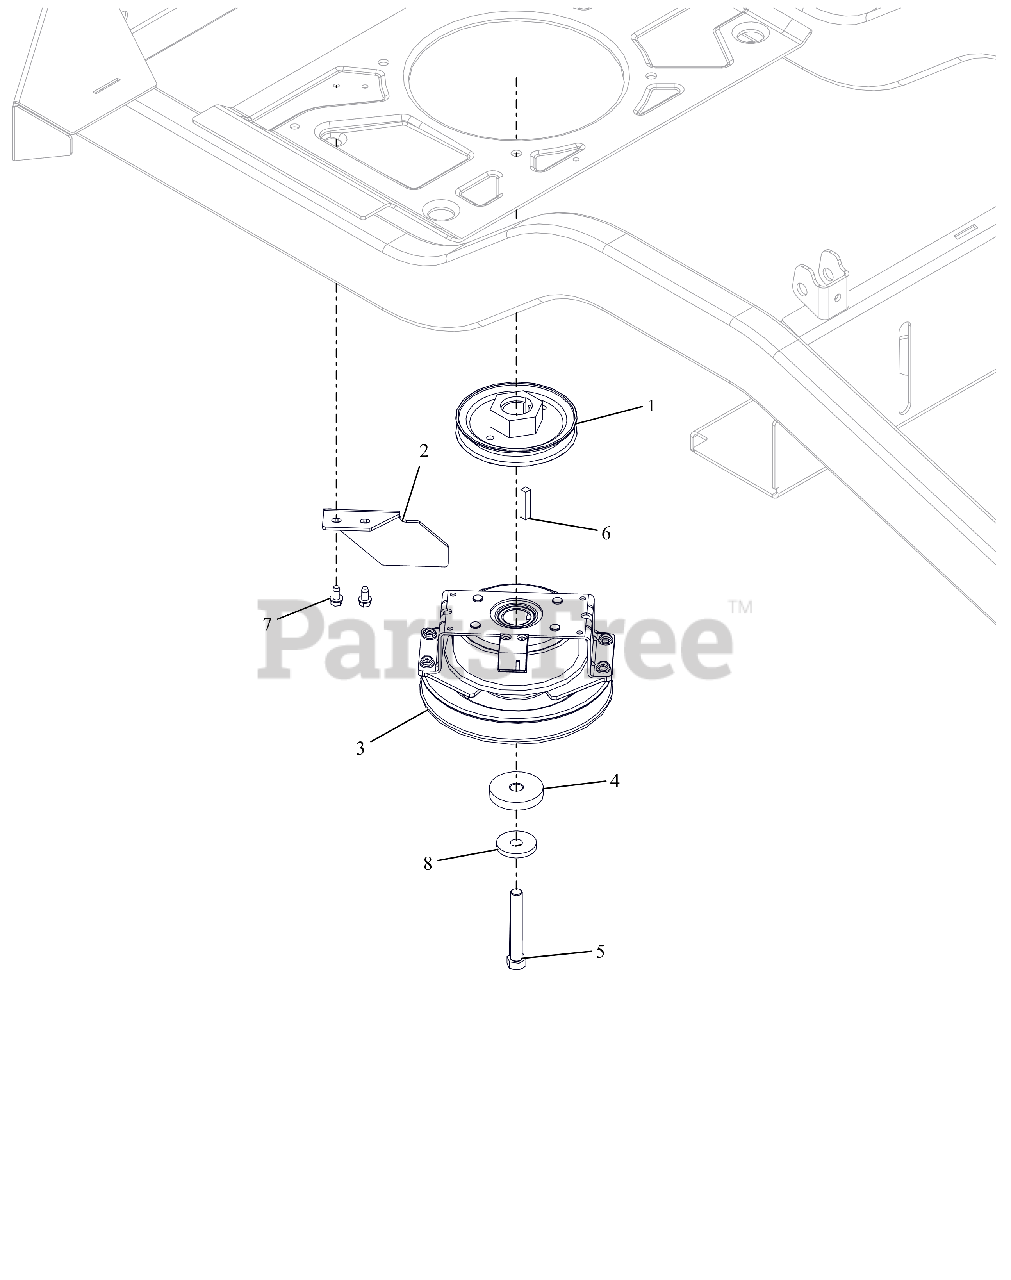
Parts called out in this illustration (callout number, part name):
1	WLDMT,PULLEY-4.50ODX1.003
2	BRKT, CLUTCH STOP HD
3	CLUTCH, OGURA DBL SPRG
4	SPACER, .474/.459X2.00X.350
5	BLT, HEX .44-20X3.00 G8 ZCC NT
6	KEY-SQ .25 X 1.25 X .25 SAE
7	SCR-TAP .25-20X.50 HWH ZCC
8	WASHER, 7/16" SPRING DISK
